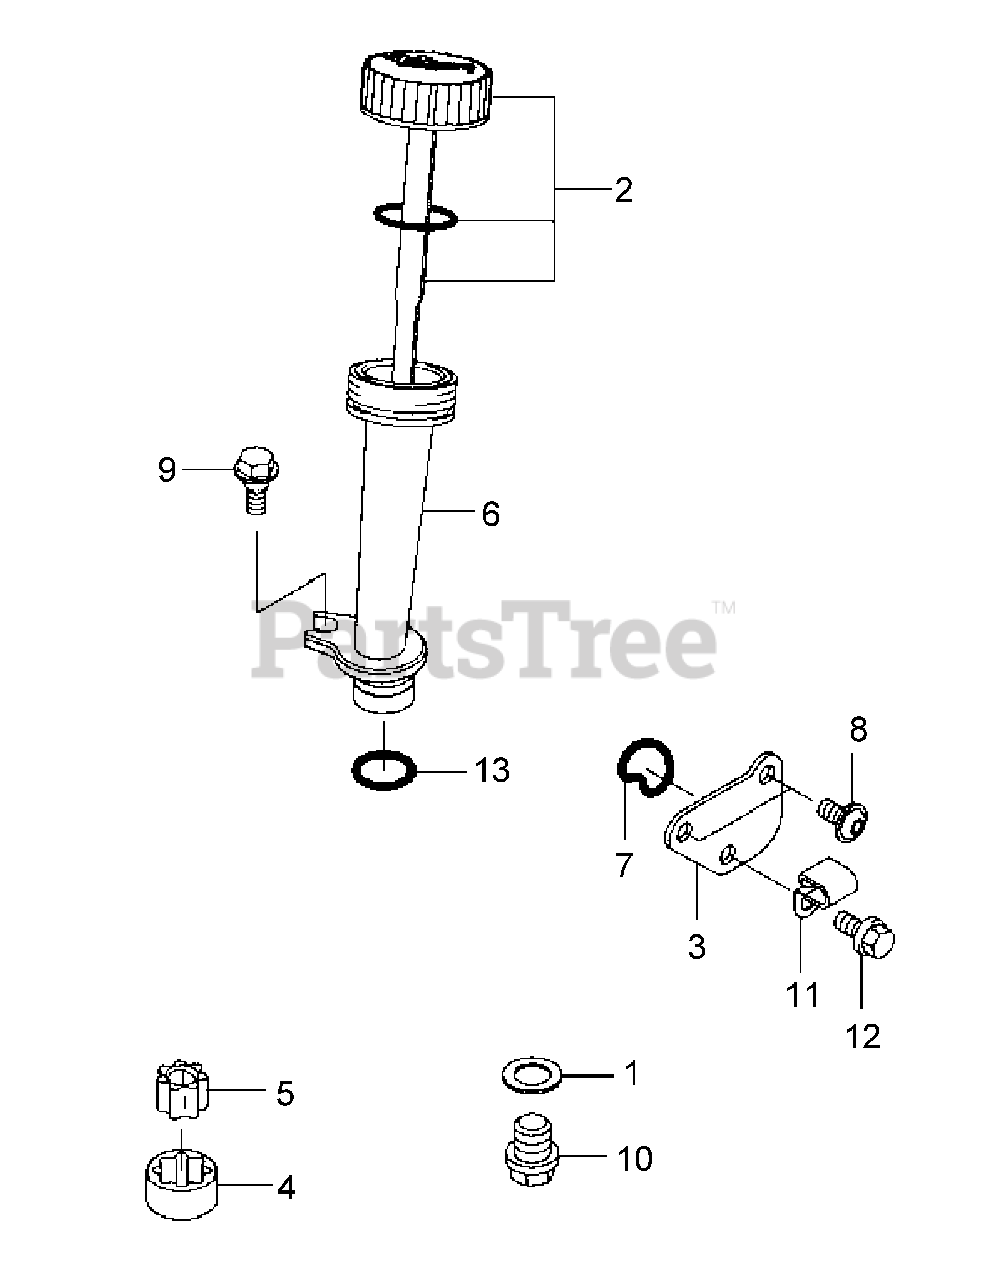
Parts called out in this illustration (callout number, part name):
1	Gasket, 12x19x1.27
2	Dipstick Cap Assy.
3	Oil Filter Cover
4	Oil Pump Rotor (Outer)
5	Oil Pump Rotor (Inner)
6	Filler Tube
8	Bolt, 6x12
12	Flanged Bolt
13	O-Ring, 16mm
